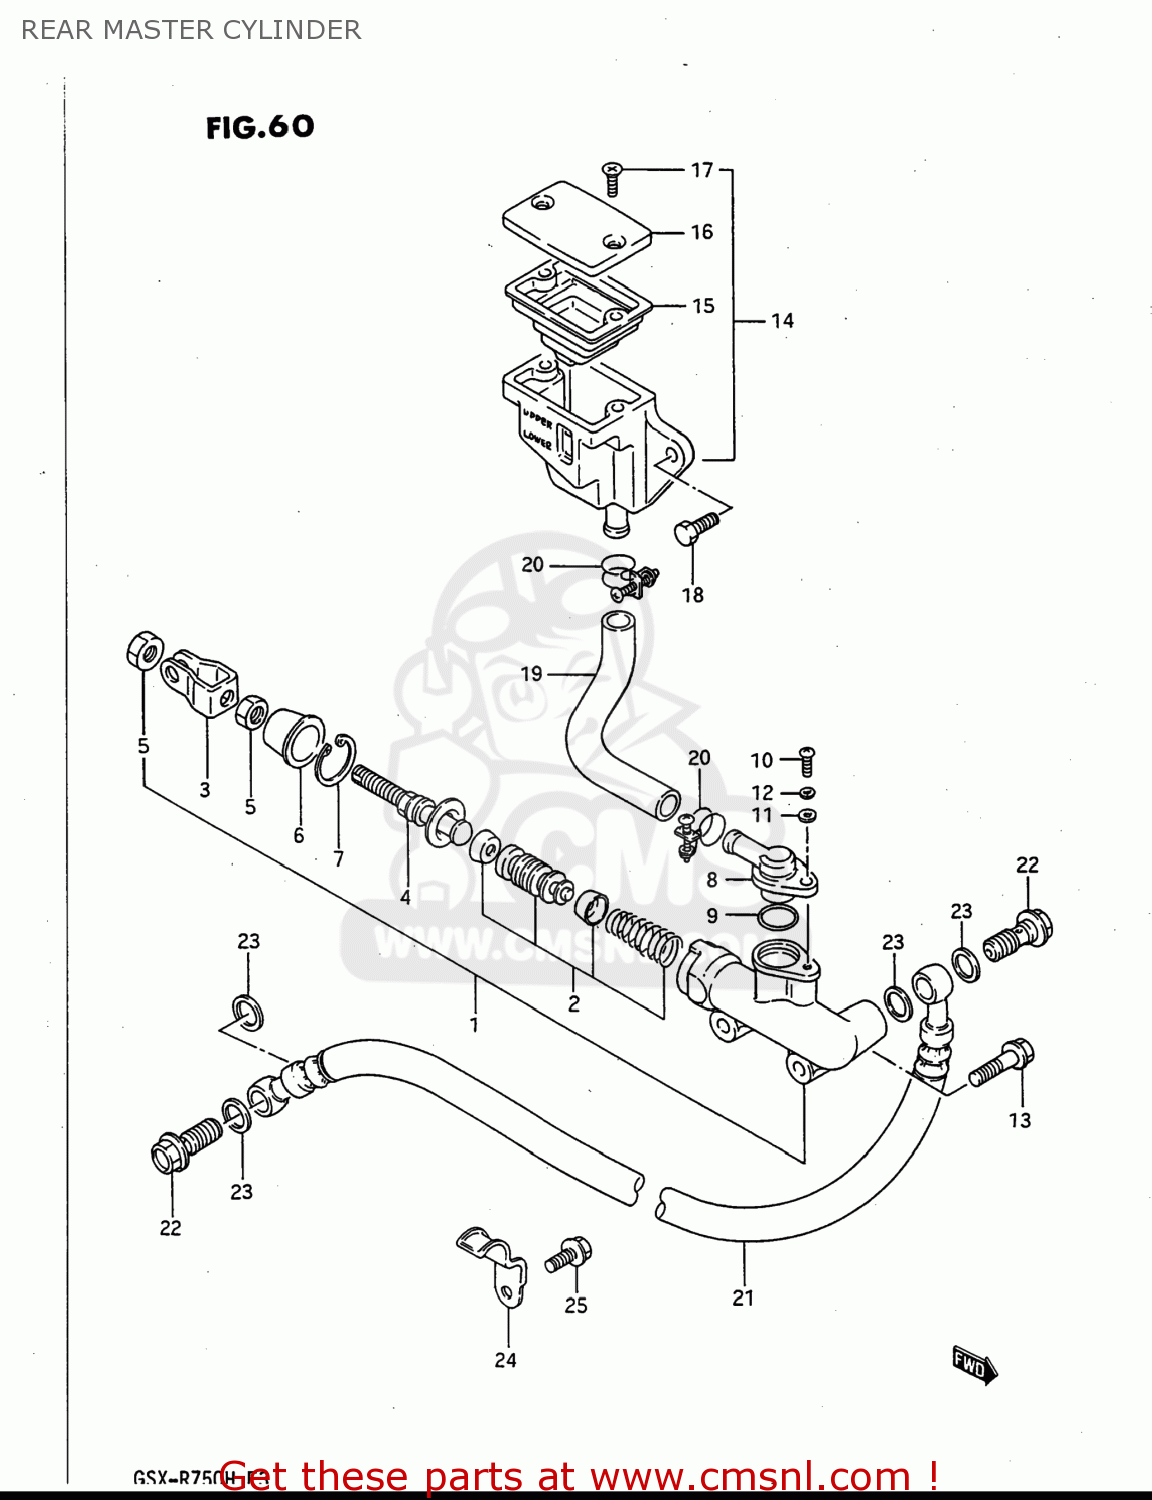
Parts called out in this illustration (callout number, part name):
1	CYLINDER ASSEMBLY,REAR MASTER
2	PISTON/CUP SET
3	YOKE
4	ROD,PUSH
5	NUT
6	BOOT
7	CIRCLIP
8	CONNECTOR
9	O RING
10	SCREW
11	WASHER
12	LOCK WASHER
13	BOLT 6X23
14	TANK ASSEMBLY,RESERVOIR
15	DIAPHRAGM
16	CAP
17	SCREW
18	BOLT
19	HOSE,RESERVOIR TANK
20	CLAMP
21	HOSE,REAR BRAKE
22	BOLT UNION
23	WASHER(10X15X1.5)
24	CLAMP,REAR BRAKE HOSE NO
25	BOLT
